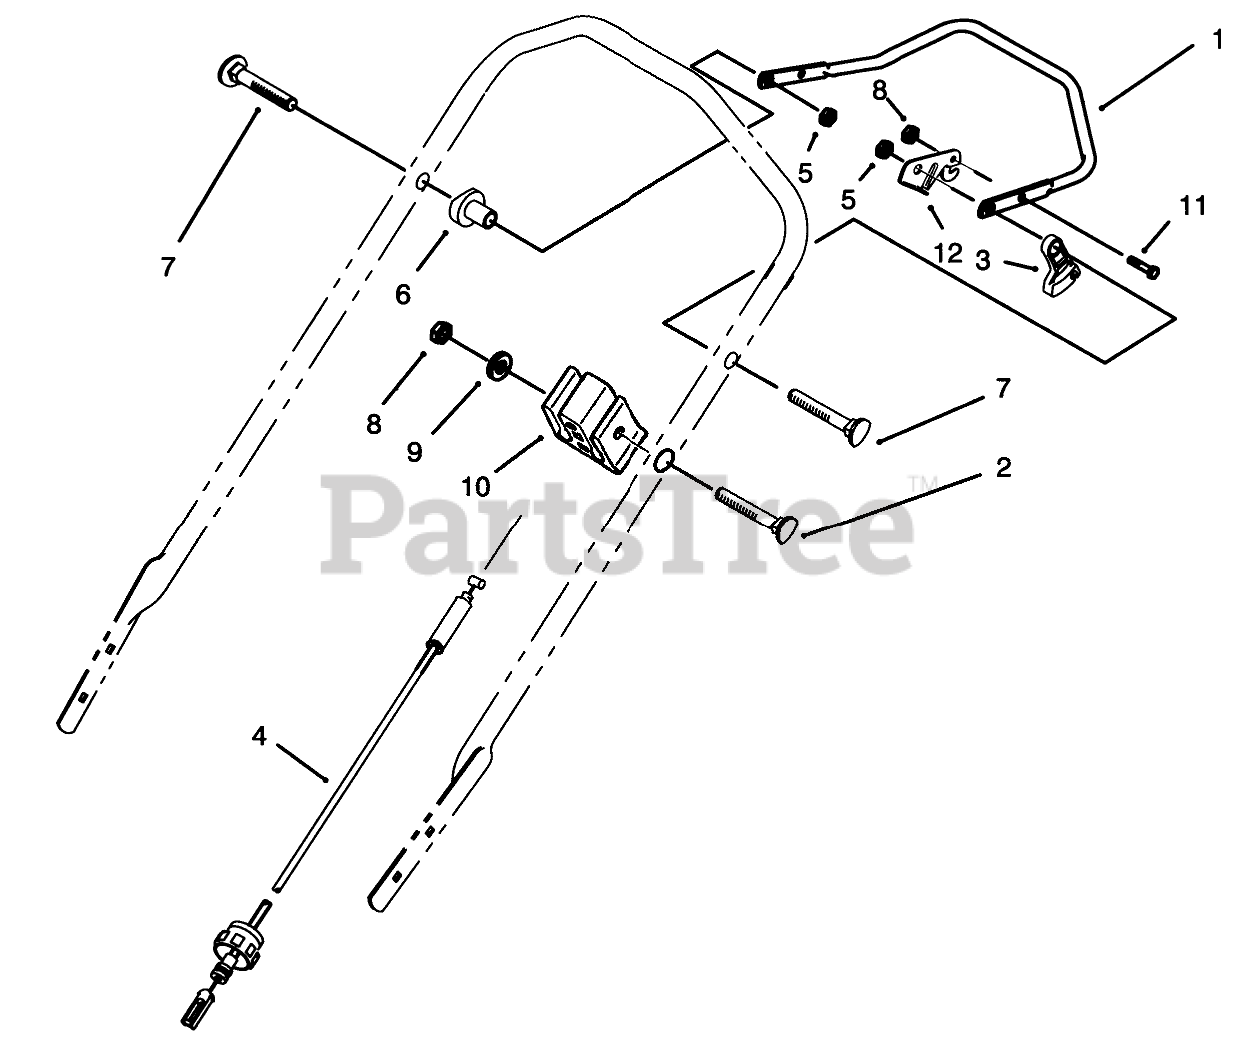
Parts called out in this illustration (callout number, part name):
1	Bar-Control
2	SCREW-HANDLE
3	LEVER-TRACTION
4	TRACTION CABLE
5	NUT-LOCK, NI
6	SPACER-SUPPORT
7	SCREW-HANDLE
8	NUT-LOCK, NI
9	WASHER-FLAT
10	SUPPORT-CABLE
11	SCREW-HH
12	CONTROL LEVER
